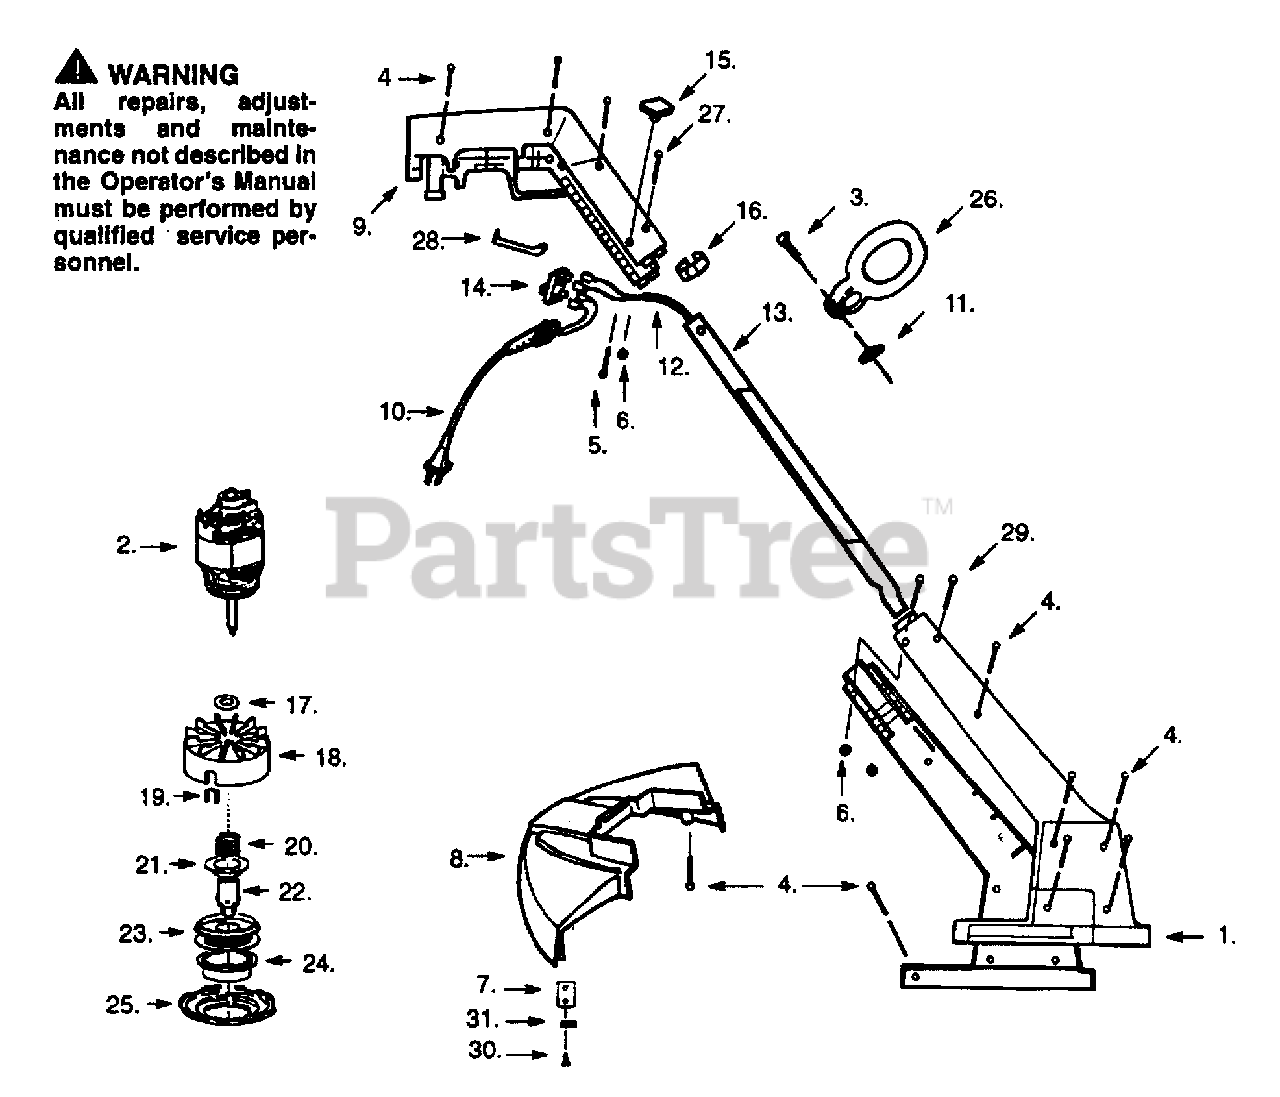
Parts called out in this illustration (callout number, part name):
5	SCREW, UPPER KNOB
6	LOCKNUT - LINE LIMITER
7	LINE LIMITER
10	CORD/PLUG ASSY
11	NUT-"D" HANDLE
16	SNAP BUTTON
19	LINE SAVER
22	DRIVING GEAR
24	RELEASE BUTTON
27	SCREW, UPPER
28	THROTTLE TRIGGER
29	SCREW, LOWER
